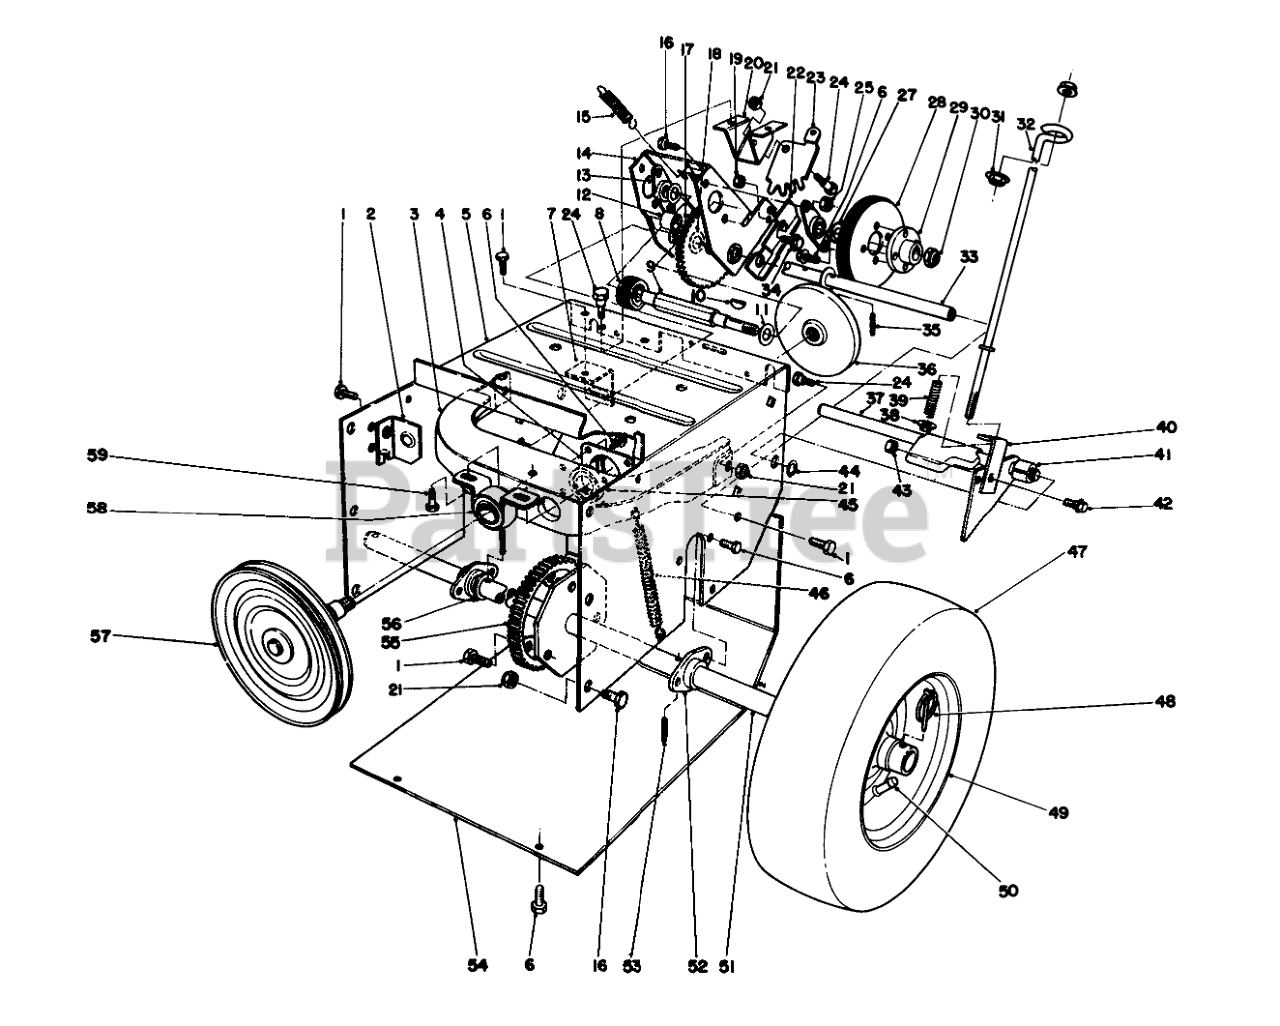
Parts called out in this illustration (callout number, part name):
1	SCREW-HWHTF
2	BRACKET-MOUNT, FRONT
3	"OBS" FRICTION PLT FRAME
4	CUP-BEARING
5	Frame-Traction
6	SCREW-HWH
7	BRACKET-MOUNT, REAR
8	PINION
9	SHAFT-WHEEL, FRICTION
10	KEY-WOODRUFF
11	WASHER-FLAT
12	5/8ID X 1LG BUSHING
13	BEARING-WHEEL, FRICTION
14	BRACKET-SLIDING
15	SPRING-TRACTION
16	SCREW-HH
17	Intermediate Gear & Bushing (Incl. Ref. #12)
18	WASHER-SPECIAL
19	NUT-LOCK, NI
20	MOUNT-LEVER
21	NUT-LOCK, NI
22	CAM-RECEIVER
23	GEAR-QUADRANT
24	BOLT-SHOULDER
25	NUT-LOCK, NI
27	WASHER-THRUST
28	WHEEL-FRICTION
29	HUB-WHEEL, FRICTION
30	NUT-LOCK, NI
31	NUT-HF
32	ROD-TRACTION, LOWER
33	SHAFT-PIVOT
34	SCREW-HH
35	PIN-SPRING
36	PLATE-FRICTION
37	Traction Engagement Asm.
38	NUT-HHF
39	SPRING
40	BRACKET-TRACTION
41	SPACER
42	SCREW
43	NUT-LOCK, NI
44	RING-RETAINING
45	BEARING-BALL
46	SPRING-PLATE, FRICTION
48	PIN-LYNCH
49	WHEEL
51	AXLE SHAFT WA
52	BEARING-AXLE
53	PIN-SPRING
54	Bottom Cover
55	GEAR-AXLE
56	WASHER-THRUST
57	Pulley & Shaft
58	BUSHING ASM
59	SCREW-HWHTF
